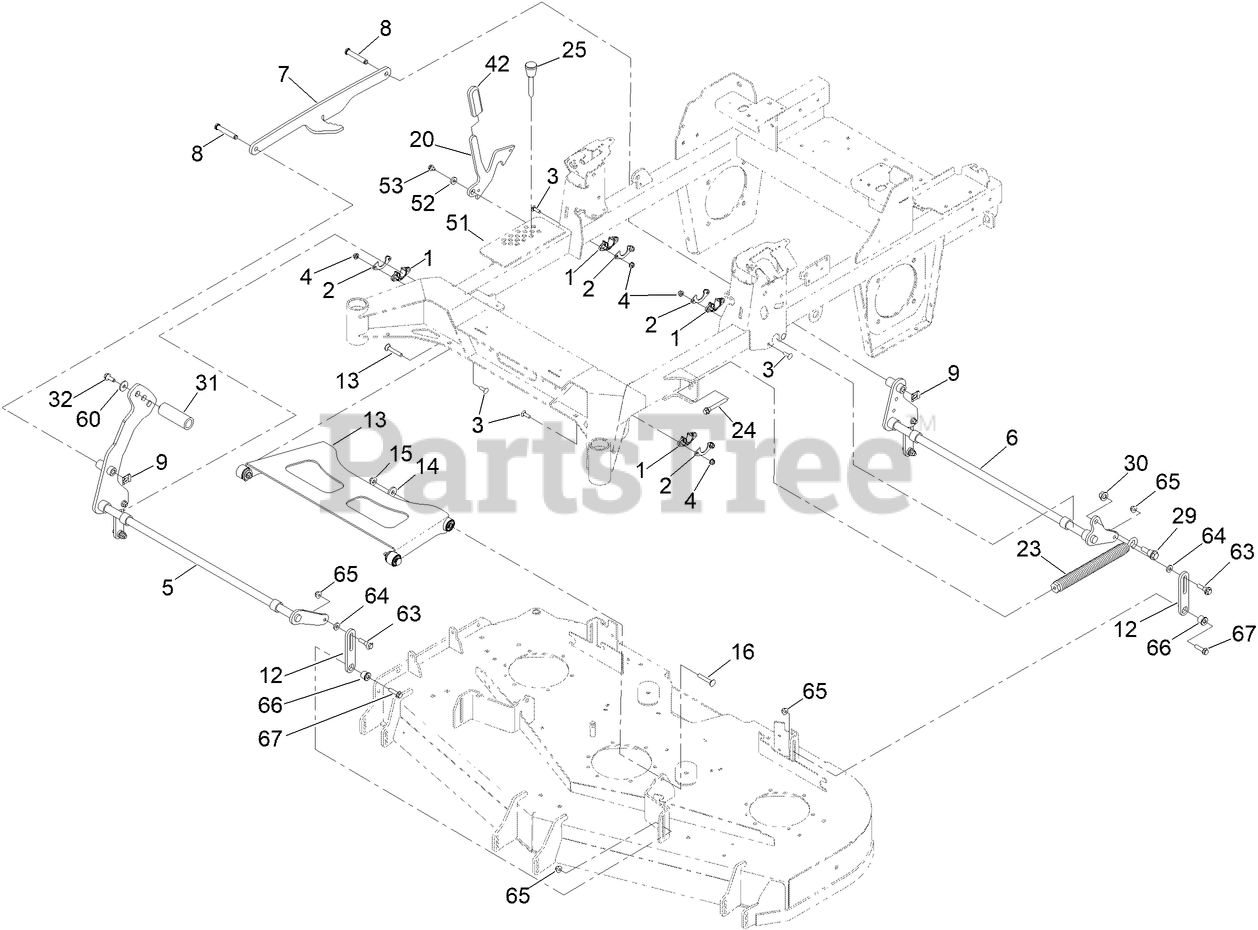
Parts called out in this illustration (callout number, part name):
1	BEARING-FLANGE
2	GUSSET-LIFT, DECK
3	SCREW-CARR
4	NUT-HF, NI
5	SHAFT-LIFT, DECK
6	DECK LIFT SHAFT ASM [BLACK]
7	LINK-LIFT
8	PIN-CLEVIS
9	CLIP-PIN
12	LINK-LIFT, DECK
13	ASM-DECK STRUT W/ BUSHINGS
14	WASHER
15	NUT-FLANGE, NI
16	SCREW-CARR
20	PLATE-TRANSPORT LOCK
23	SPRING-EXTENSION
24	BOLT-SHOULDER
25	PIN-HOC
29	SCREW-SHOULDER, HHF
30	NUT-LOCK
31	PEDAL-FOOT LIFT
32	SCREW-HHF
42	GRIP-LEVER
51	DECAL-HOC
52	SPACER
53	SCREW
60	WASHER
63	BOLT-SHOULDER
64	SPACER
65	NUT-HF, NI
66	BUSHING-DECK LIFT
67	SCREW-HHF
